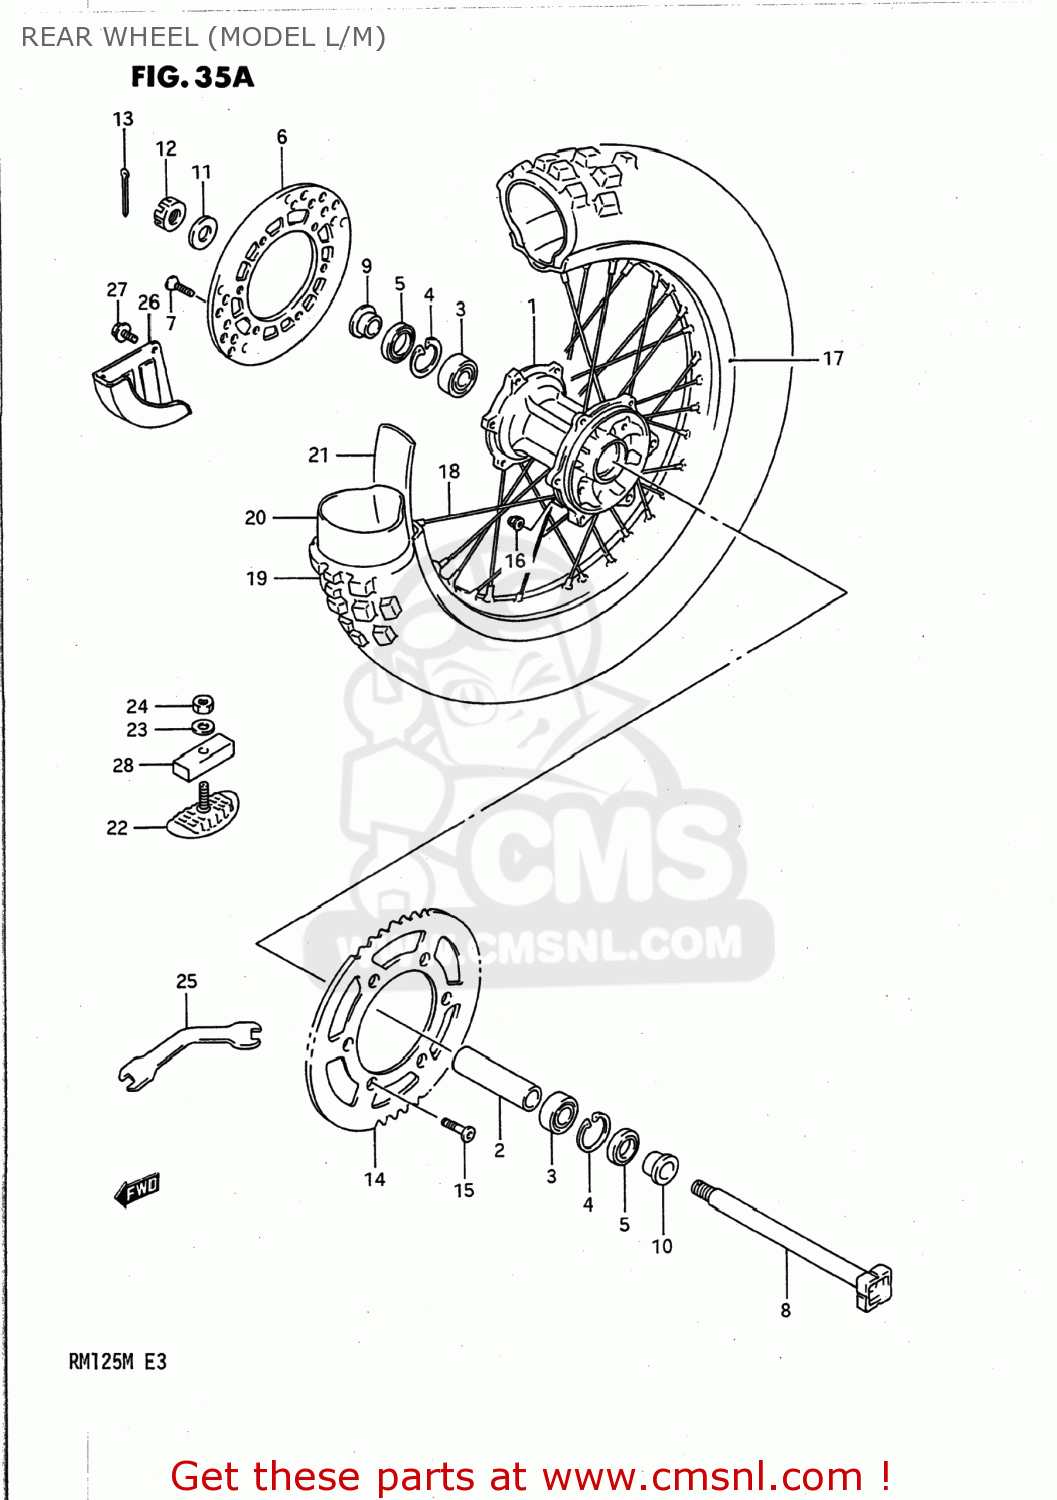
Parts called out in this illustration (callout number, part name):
1	HUB,RR
2	SPACER,RR HUB BEARING
3	BEARING WHEEL REAR(20X47X14)
4	CIRCLIP
5	SEAL,OIL(26X47X5)
6	DISC,REAR BRAKE
7	SCREW
8	AXLE,RR
9	SPACER,RR AXLE,R
10	SPACER,RR AXLE,L
11	WASHER (19X32X3.2)
12	NUT 18MM
13	PIN,COTTER
14	SPROCKET,REAR
15	BOLT(8X30.5)
16	NUT
17	RIM,REAR WHEEL (1.85X19)(A
18	SPOKE SET,REAR WHEEL
19	TIRE
20	TUBE ASSEMBLY,WHEEL,INNER
21	PROTECTOR,WHL INR TUBE
22	STOPPER,BEAD
23	WASHER
24	NUT
25	SPANNER,OPEN
26	COVER,REAR DISC
27	BOLT
28	CUSHION,BEAD STOPPER
